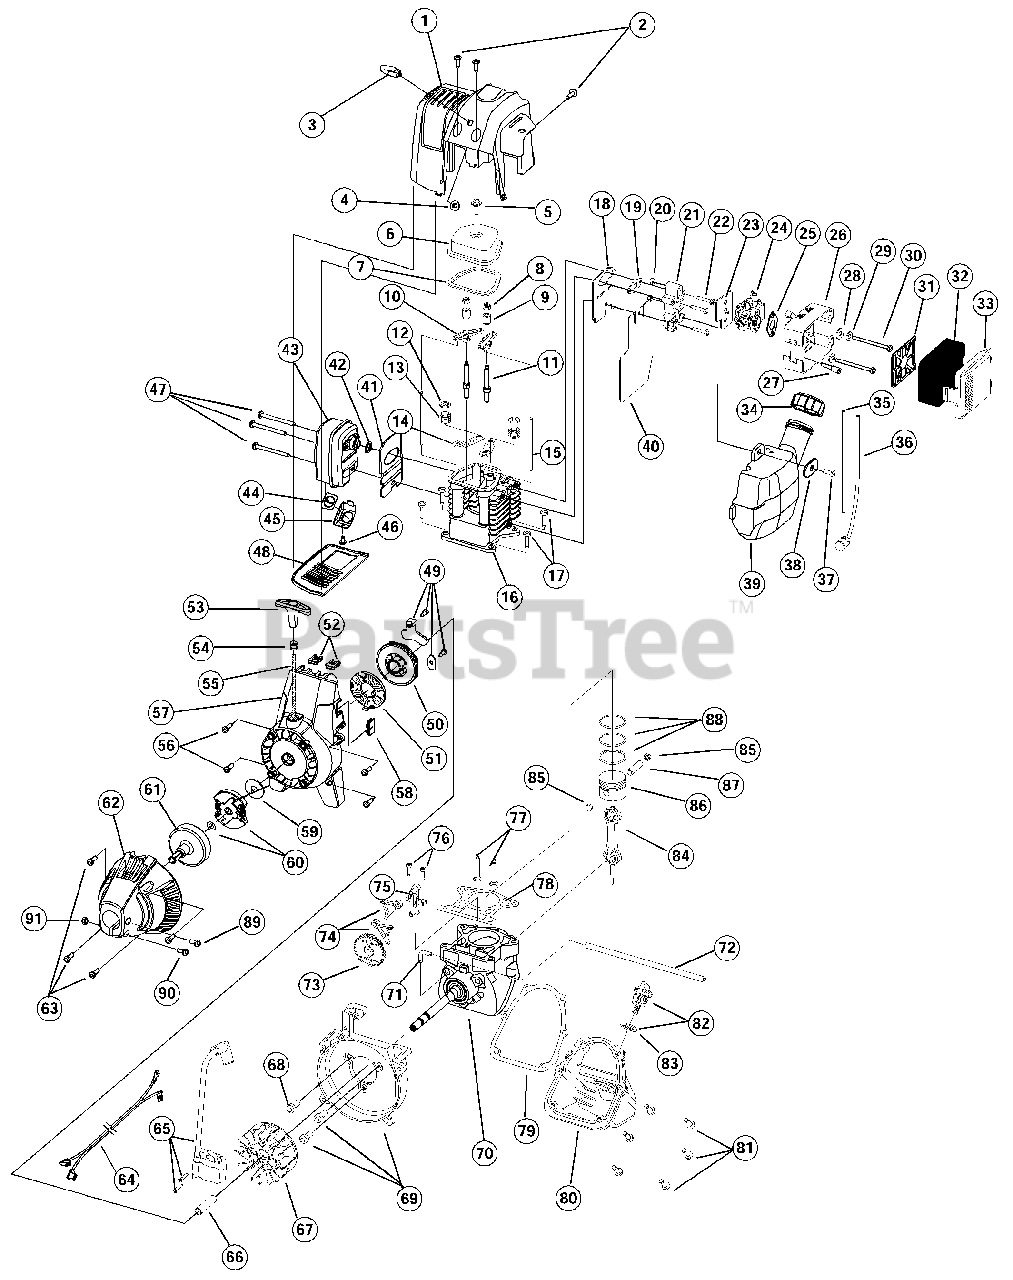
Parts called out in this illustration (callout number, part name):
1	Engine Cover
2	Engine Cover Screws
3	Starter Rope Eyelet
4	Eyelet Nut
5	Valve Cover Screw
6	Valve Cover
7	Valve Cover Gasket
8	Rocker Adjustment Nut
9	Rocker Arm Pivot
10	Rocker Arm
11	Rocker Arm Stud
12	Valve Spring Retainer
13	Valve Spring
14	Push Rod Guide
15	Push Rod
16	Cylinder Assembly
17	Cylinder Screw
18	Intake Baffle
19	Carburetor Mount Gasket
20	Nut
21	Carburetor Mount
22	Carburetor Mount Screw
23	Carburetor Gasket
24	Carburetor with Primer
25	Air Filter Gasket
26	Air Filter Cover Assembly
27	Breather Tube Assembly
28	Grommet Washer
30	Air Filter Mounting Screw
31	Air Filter Plate
32	Air Filter
33	Air Filter Cover
34	Fuel Cap
35	Fuel Return Line
36	Fuel Pick-Up Line with Filter
39	Fuel Tank Assembly
40	Fuel Tank Shield
41	Muffler Baffle
42	Muffler Gasket
43	Muffler
44	Spark Arrestor Screen
45	Screen Cover
47	Muffler Mounting Screw
48	Muffler Cover
49	Pulley Retainer Assembly
50	Recoil Pulley
51	Recoil Spring
52	Nut Clip
53	Pull Handle
54	Rope Guide
56	Starter Housing Screw
57	Starter Housing Assembly
58	Wire Grommet
59	Clutch Washer
60	Clutch with Washer
61	Clutch Drum
62	Clutch Cover
63	Clutch Cover Screw
64	Lead Wire
65	Ignition Module with Screws
67	Flywheel
69	Shroud Assembly with Screws
70	Crankcase Assembly
71	90° Elbow
72	Breather Hose
73	Cam Gear
74	Cam Follower
75	Cam Bracket
76	Cam Bracket Screw
77	Valves, Intake and Exhaust
78	Cylinder Gasket
79	Oil Pan Gasket
80	Oil Pan
81	Oil Pan Screw
82	Dipstick Assembly
84	Connecting Rod
85	Wrist Pin Button
86	Piston
87	Wrist Pin
88	Piston Ring Set
89	Anit-Rotation Screw
90	Screw
